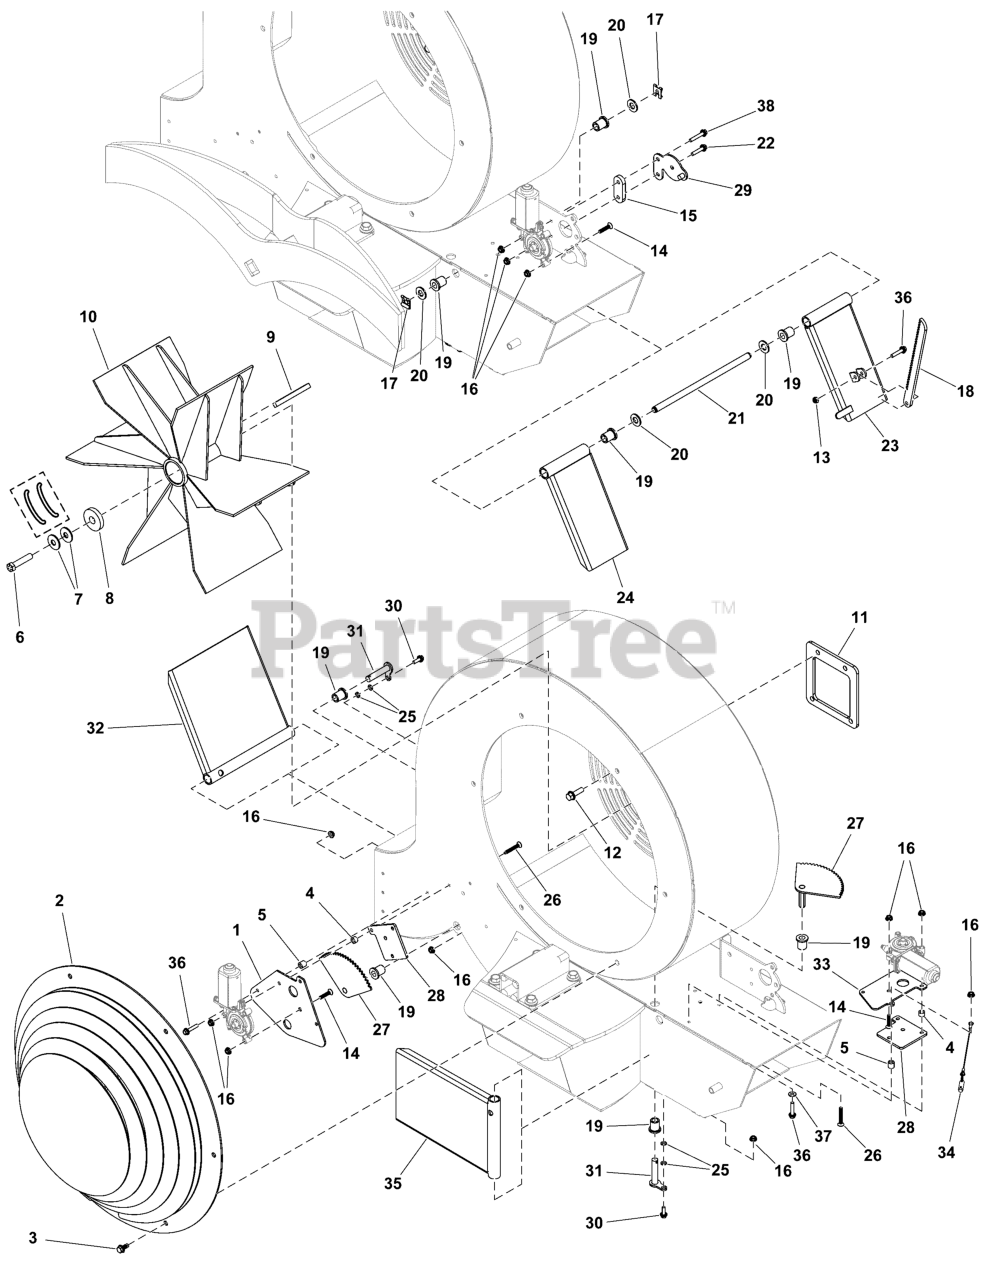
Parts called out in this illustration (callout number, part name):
1	PLATE, RIGHT DEFLECTOR COVER - BLK
2	WELD, SAFETY COVER Z3 - BLK
3	SCREW, 5/16-18x0.750, GR5, WHIZ-LOCK, ZC
4	SPACER, .265 X .50 X .320, CZ
5	SPACER, .265 X .50 X .483, CZ
6	BOLT, 5/8-18 X 2-1/4 GD8, PHOS
7	BELLEVILLE WASHERS 1.750 X .656 X .140
8	WASHER, 5/8 X 2" OD
9	KEY, 3/8 SQ X 3.75
10	WELD, IMPELLER, 20.30 OD
11	PLATE, SPACER, Z3, CZ
12	BOLT, 3/8-16 X 1, FLANGE, GD 5, CZ
13	NUT, 1/4-20 HEX NYLON LOCK
14	SCREW, 1/4-20 X 1-1/4, ALLEN, SS
15	PLATE, RACK SPACER - BLK
16	NUT, 1/4-20 HEX SERR. FLANGE
17	CLIP, SAFETY
18	PLATE, DEFLECTOR RACK,CZ
19	BUSHING, 1/2 X 3/4 X 1F
20	WASHER, 1/2 SAE
21	ROD, DEFLECTOR SUPPORT, Z3000
22	BOLT, 1/4-20 X 1-1/2, FLANGE, CZ
23	WELD, LEFT POWER DEFLECTOR, Z3000, CZ
24	WELD, LEFT SLAVE DEFLECTOR, Z3, CZ
25	WASHER, 1/4 LOCK
26	SCREW, 1/4-20 X 1-3/4, ALLEN, SS
27	WELD, UNIVERSAL DEFLECTOR GEAR - BLK
28	PLATE, DEFLECTOR SPACER - BLK
29	WELD, RACK KEEPER, CZ
30	BOLT, 1/4-20 X 3/4, FLANGE, CZ
31	WELD, FORWARD DEFLECTOR PIN, CZ
32	WELD, RIGHT DEFLECTOR, Z3000, CZ
33	PLATE,FW DEFLECTOR MOTOR MNT - BLK
34	Z DEFLECTOR PIN RETAINING CABLE (Pin & Lanyard Assembly)
35	WELD, FRONT DEFLECTOR, Z3000, CZ
36	BOLT, 1/4-20 X 1-1/4, FLANGE, CZ
37	WASHER, 1/4 SAE
38	BOLT, 1/4-20X1-3/4, SER FLG GD5, TFL, CZ
